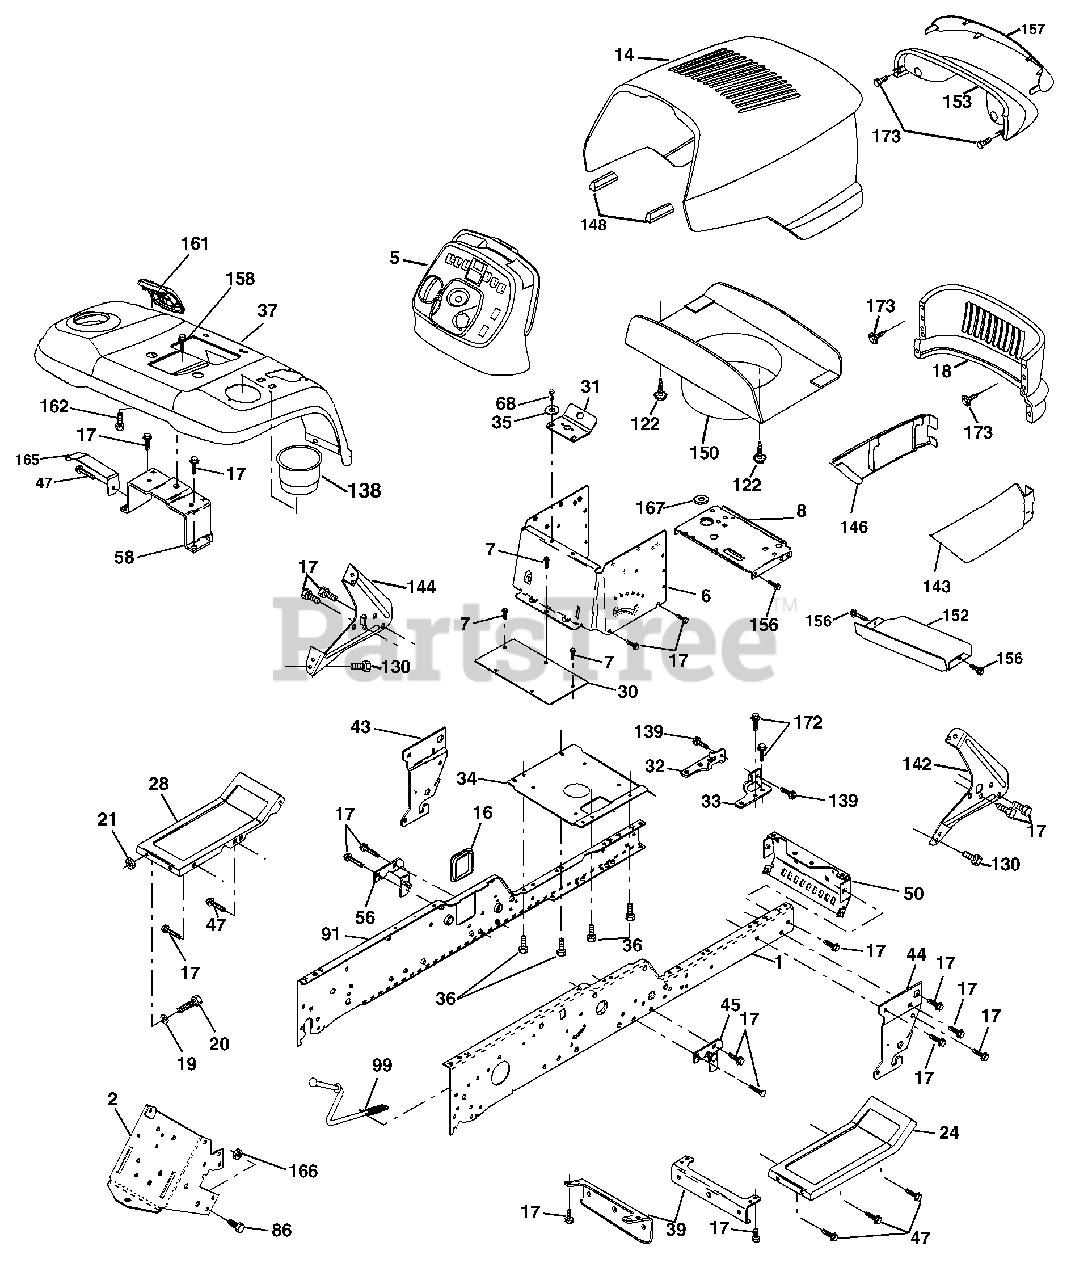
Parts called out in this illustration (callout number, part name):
1	Rail, Frame RH
2	Drawbar, Gt
5	Dash
6	Dash, Lower Vgt One Piece
7	Screw, Thd Cut 1/4-20 x 1/2
8	Support, Battery
14	Hood Asm
16	Cover, Access
17	Screw 3/8-16 x .75
18	Grille
19	Washer 13/32x13/16 x 12 Ga.
20	Bolt, Fin Hex 3/8-16 x 1
21	Nut Crownlock 3/8-16 unc
24	Footrest, RH
28	Footrest, LH
30	Saddle, Hydro
31	Brace, Supt 1-pc VGT
32	Bracket, Pivot Chassis Lh
33	Bracket, Pivot Chassis Rh
34	Plate Asm Engine
35	Washer 11/32 x 11/16 x 16 Ga.
36	Screw 5/16-18 x 3/4
37	Fender Pnt
39	Bracket, Axle Front
43	Bracket, Spnsn Front Lh
44	Bracket, Spnsn Front Rh
45	Bracket Asm., Susp Chas.Rh
47	Screw Thdrol. 3/8-16 x 1/2
50	Bracket, Chassis Front
56	Bracket Asm., Susp Chas. Lh
58	Bracket Asm., Fender
68	Screw Thdrol. 5/16-18 x 1/2
86	Bolt Fin Hex 7/16-14 unc x 1
91	Rail, Frame Lh
99	Rod By Pass
122	Screw Hex Wshd 8-18 x 7/8
130	Screw Hwhd Hi-Lo #13-16 x 3/4
138	Cup Holder
139	Bolt Shoulder 5/16-18 TT
142	Bracket Dash Rh
143	Skirt Grille Rh
144	Bracket Dash Lh
146	Skirt Grille Lh
148	Extrusion Bumpers
150	Duct Heat Hood
152	Shield Browning
153	Lens Asm.
156	Screw 5/16-18 x 3/4
157	Lens Bar
158	Screw Thdrol 3/8-16 x 1/2
161	Console Fuel Window
162	Screw Hex 1/4-1/2 unc
165	Bracket Support Tank
166	Nut 7/16-14
167	Bushing-Snap Nylon
172	Screw 3/8-16 x .875
173	Screw 10 x 3/4 Single Lead-Hex
